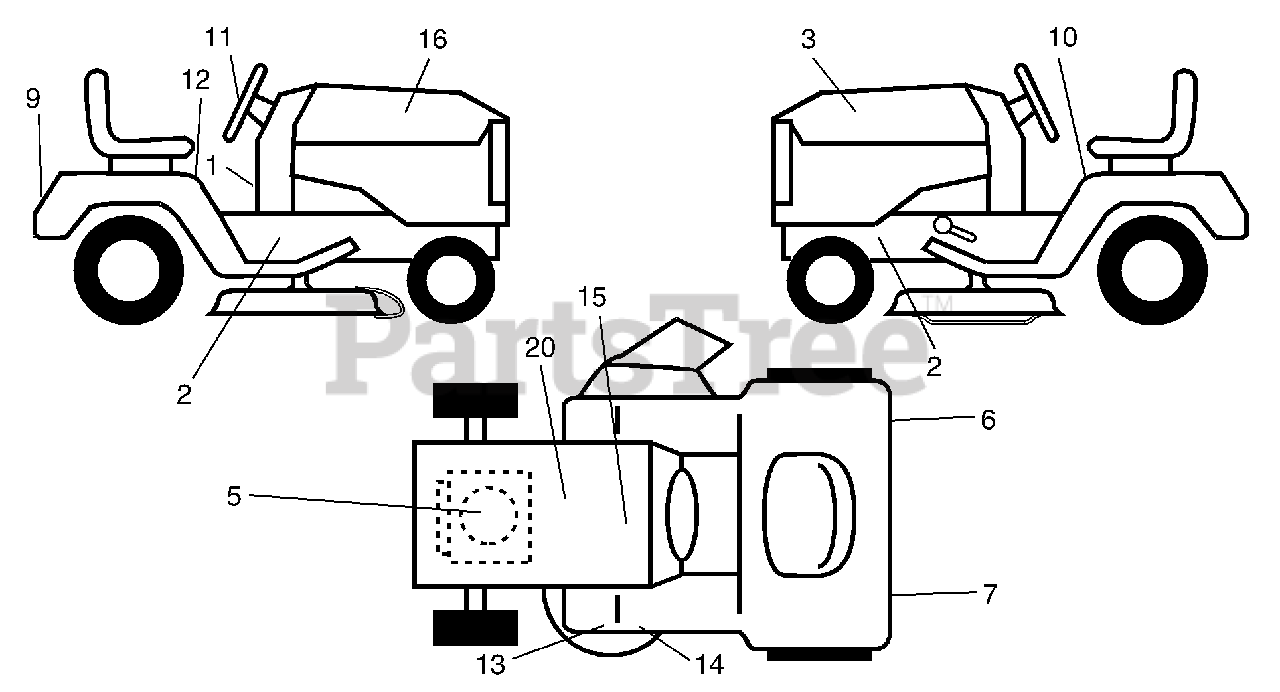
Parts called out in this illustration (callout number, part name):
1	Decal Dash
2	Decal Chassis 25/48 Statesman
3	Decal Hood LH
5	Decal HP Engine
6	Decal Reflector Rh
7	Decal Reflector Lh
9	Decal Fender Logo
10	Decal Fender Danger
11	Decal Ins Strg Whl
12	Decal Fender Oper Cruise
13	Decal Deck Caution
14	Decal V-Belt Schematic
15	Decal Replace
16	Decal Hood Rh
20	Decal Bat Dan/Psn
20	Decal By Pass
